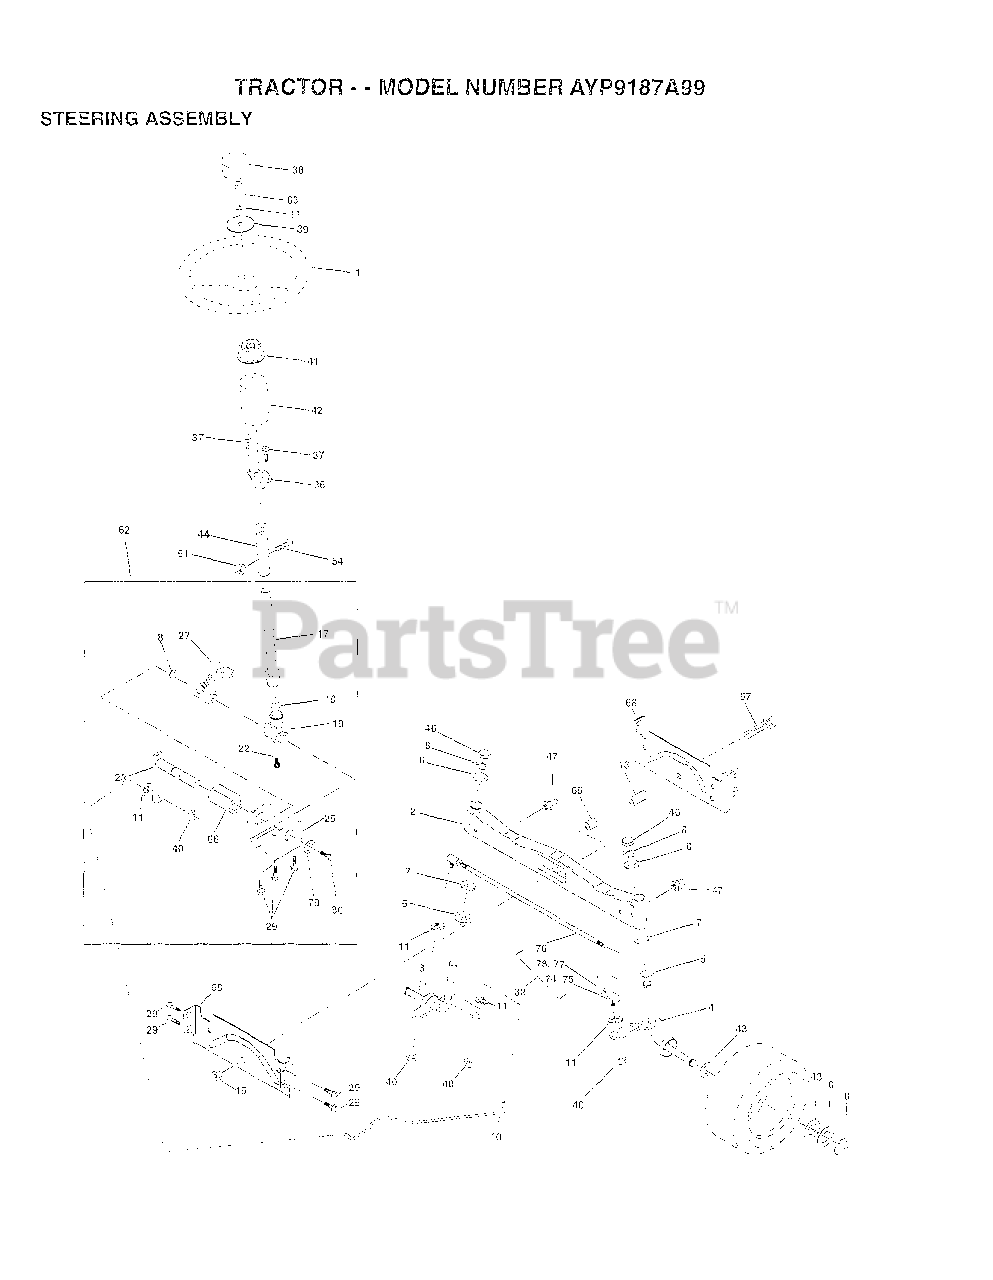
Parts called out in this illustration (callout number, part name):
1	WHEEL STR AYP BLK
3	"SPINDLE ASM,LH"
4	"SPINDLE ASM,RH"
5	WASHER .T
6	WASHER
7	WASHER
8	RING
10	LINK.DRAG
11	LOCKWASHER
13	BEARING.FRT.SPACER.AXLE
15	"NUT-LOC,FLANGE LT"
17	SHAFT ASM STEERIN
18	WASHER THRUST
19	SUPPORT.SHAFT.STEER
22	SCREW.HX.WSH.HD
23	SHAFT.ASM.PITMAN
25	BRKT-STEERING
27	GEAR SECTOR
29	SCREW
32	ROD.ASM.TIE.BALL
36	BUSHING.STEERING
37	"SCREW-TT,10-32 FL"
38	CAP STEER AYP
39	WASHER T
40	GRIPCO NUT
41	ADAPTER LT
42	BOOT.STEER.PL
43	WASHER
44	EXT SHAFT STEERIN
46	CAP
47	ZERK M
51	NUT
54	BOLT
62	KIT.STEER.ASM
63	BOLT
65	SPACER AXLE
66	"BEARING-ARM,PITMA"
67	BOLT
68	BRACE AXLE
74	JOINT.RH
75	JOINT.LH
77	NUT
78	NUT
79	WASHER
80	BOLT.HX.NYLON3/8-16X3/
